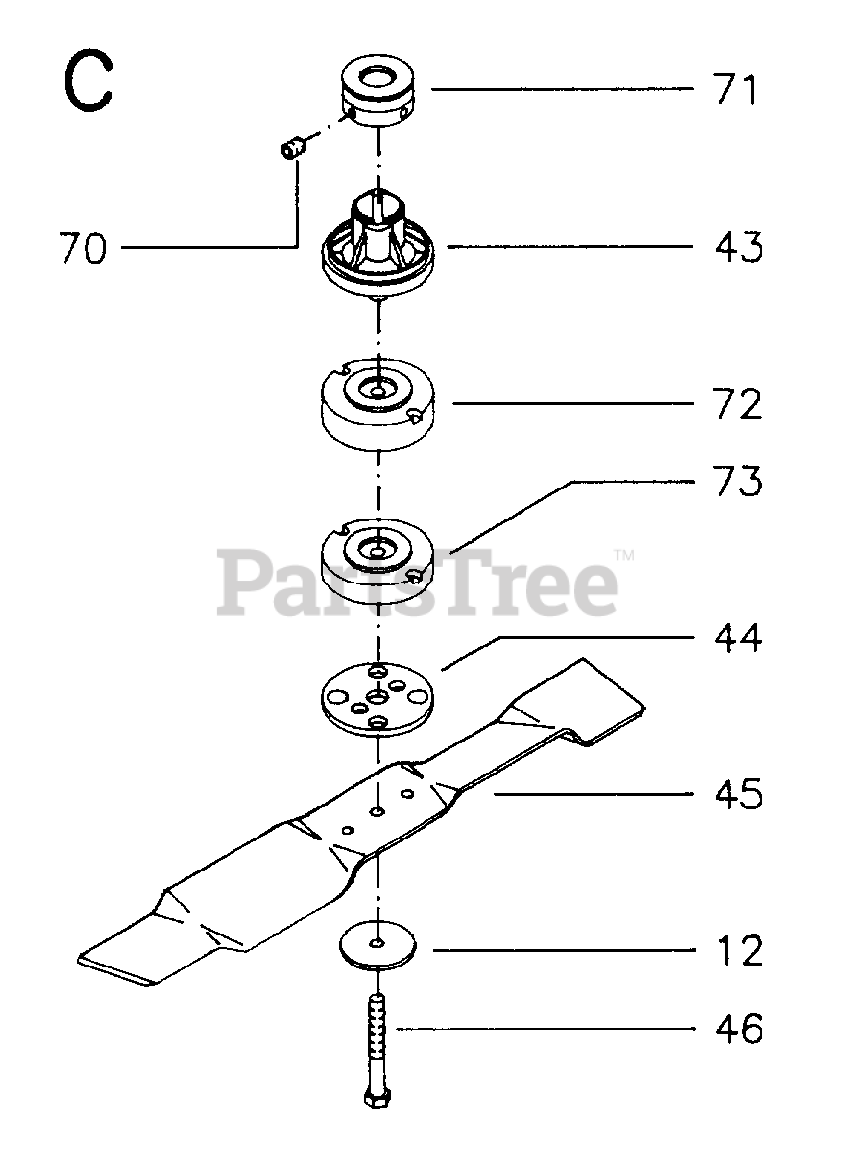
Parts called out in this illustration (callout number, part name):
44	STEEL PLATE ADAPTER
72	SPACER
73	SPACER
